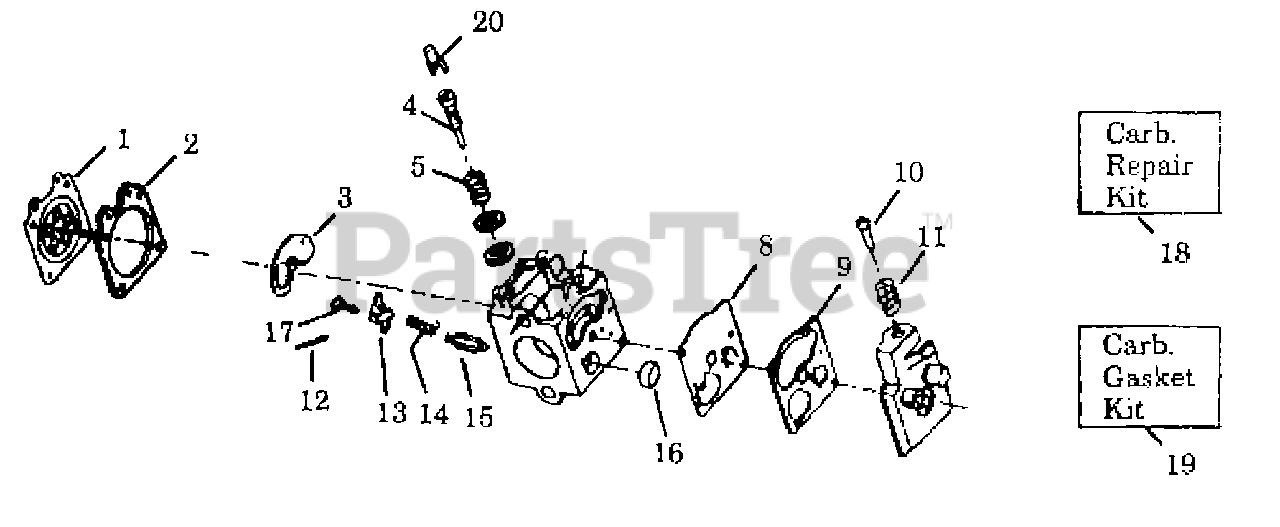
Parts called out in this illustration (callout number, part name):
1	Metering Diaphragm
2	Metering Diaphragm Gasket
3	Circuit Plate Gasket
4	Mixture Needle Type 1
4	Mixture Needle Type 2
5	Mixture Needle Spring Type 1
5	Mixture Needle Spring Type 2
6	Mixture Needle Washer
7	"O" Ring Mixture
8	Fuel Pump Diaphragm
9	Fuel Pump Gasket
10	Idle Speed Screw
11	Idle Speed Spring
12	Metering Lever Pin
13	Metering Lever
14	Metering Lever Spring
15	Inlet Needle Valve
16	Fuel Inlet Screen
17	Metering Lever Pin Screw
18	Carb. Kwik Repair Kit
19	Carb. Gasket/Diaphragm Kit
20	Limiter Cap - Type 2
